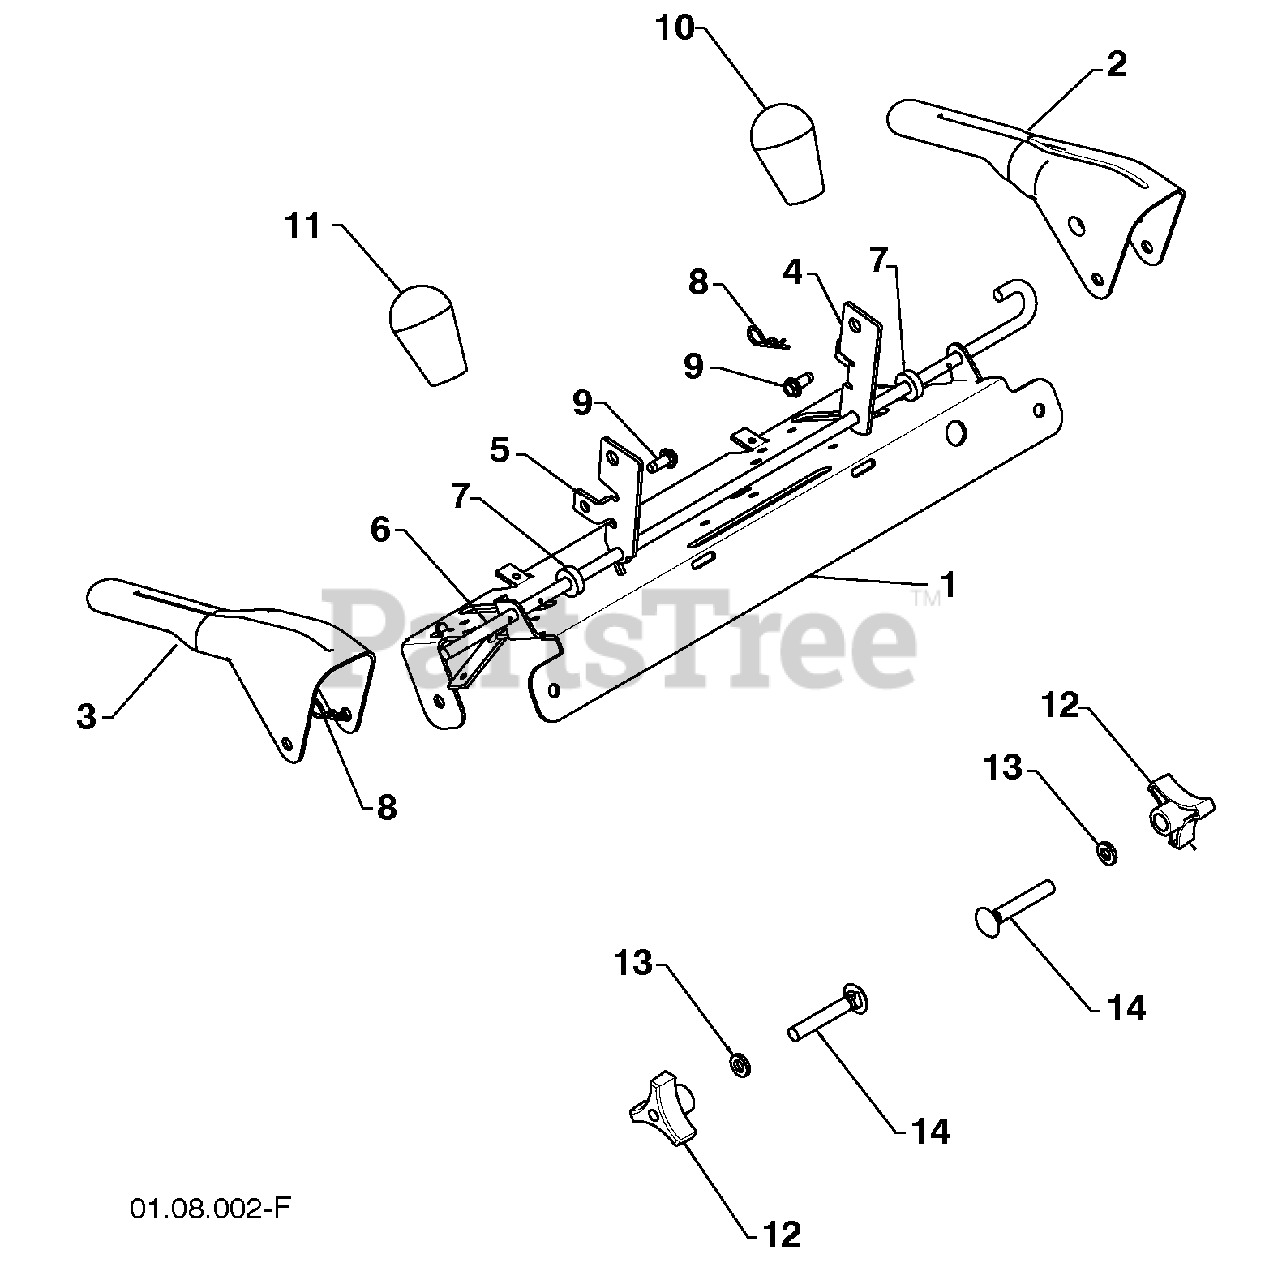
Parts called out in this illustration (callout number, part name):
1	CONTROL PANEL
2	CONTROL LEVER LH
3	CONTROL LEVER RH
4	TRACTION ROD ARM
5	IMPELLER ROD ARM
6	INTERLOCK ROD
8	RETAINER
9	SCREW 1/4-20 X .62
10	KNOB BLACK
11	KNOB RED
12	HANDLE KNOB
13	WASHER 3/8
14	CARRIAGE BOLT 3/8-16 X 2.25
